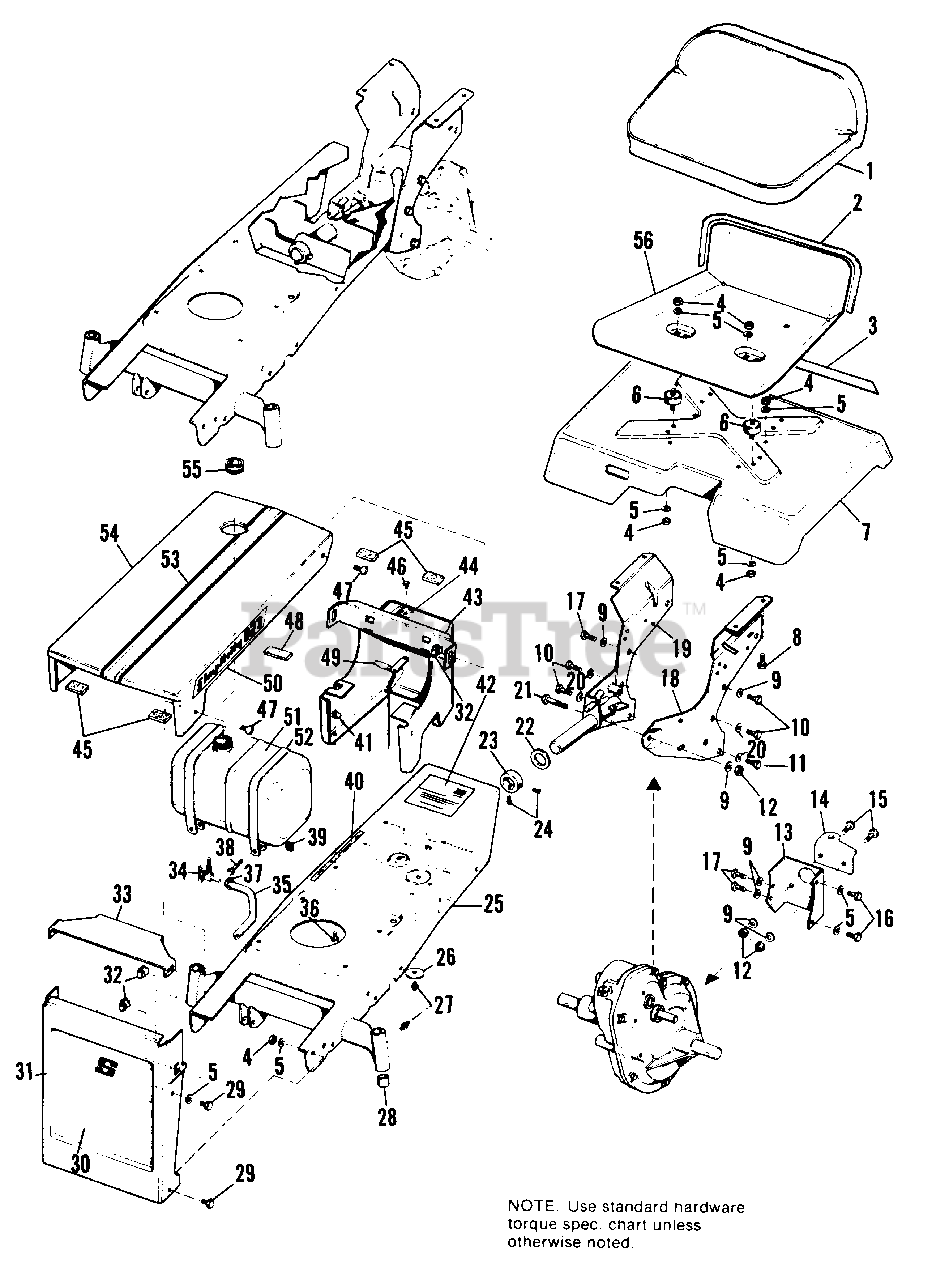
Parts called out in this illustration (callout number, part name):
1	PAD, Seat
2	TAPE, Seat Pan, 2 Feet
3	DECAL, Yeoman
4	NUT, Hex, 5/16-18
5	LOCKWASHER, 5/16
6	CONNECTOR, Cushion
7	SUPPORT, Seat (990486 & 990542 Only)
7	SUPPORT, Seat
8	CAPSCREW, Hex Hd., 5/16-18 x 3/4
9	LOCKWASHER, 3/8
10	CAPSCREW, Hex Hd., 7/16-14 x 1
11	CAPSCREW, Hex Hd., 3/8-16 x 7/8
12	NUT, Hex, Full, 3/8-16
13	BRACKET, Draw Bar
14	CLIP, Draw Bar
15	CAPSCREW, Hex Hd., 3/8-16 x 1
16	CAPSCREW, Hex Hd., 5/16-18 x 1-1/4
17	CAPSCREW, Hex Hd., 3/8-16 x 3/4
17	FRAME ASSY. (990415 Only)
18	PLATE, Side, L.H.
18	PLATE, Side, L.H. (990415 Only)
19	PLATE ASSY., R.H.
19	PLATE ASSY., R.H. (990415 Only)
20	LOCKWASHER, 7/16
21	CAPSCREW, Hex Hd., 3/8-16 x 1-1/4
23	COLLAR, Set
24	SETSCREW, 5/16-18 x 1/2
25	FRAME ASSY.
26	WASHER, Plain, #10
27	FITTING, Grease
29	CAPSCREW, Hex Hd., 5/16-18 x 5/8
30	DECAL, Grille
32	NUT, Retainer
33	SUPPORT, Grille
34	VALVE, Shutoff
35	HOSE, Fuel
36	SCREW, Self Tapping, Hex Hd., #14 x 5/8
37	CLAMP, Hose
38	SCREW, Machine, Fillister Hd., 1/4-20 x 1-3/4
39	NUT, Square, 1/4-20
40	DECAL, Clutch
41	NUT, speed
42	DECAL, Safety
42	DECAL, Safety (990415 Only)
43	DASH ASSY.
44	DECAL, Throttle
45	PAD, Felt
46	SCREW, Self Tapping, Hex Hd., 1/4-20 x 1/2
47	SCREW, Thumb, 5/16-18 x 3/4
48	GASKET, Felt
49	CONTROL, Choke
50	DECAL, Number
50	DECAL, Number (990415 Only)
51	TANK, Fuel
52	STRAP, Tank
53	STRIPE, Hood
55	CAP, Fuel Tank
56	PAN, Seat
